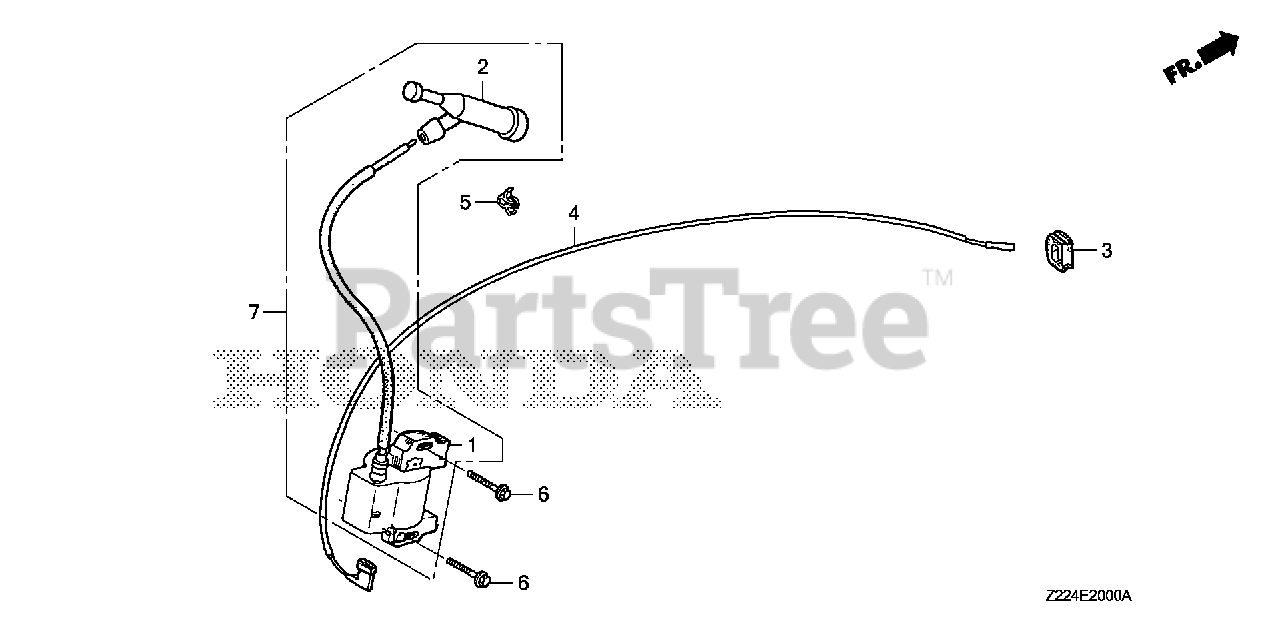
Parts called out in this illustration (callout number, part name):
1	COIL ASSY., IGNITION
2	CAP ASSY., NOISE SUPPRESSOR (NGK Y-EZD)
3	GROMMET, WIRE
4	WIRE, STOP SWITCH (470MM)
5	HOLDER, STOP SWITCH WIRE
6	BOLT, FLANGE (6X28) (CT200)
